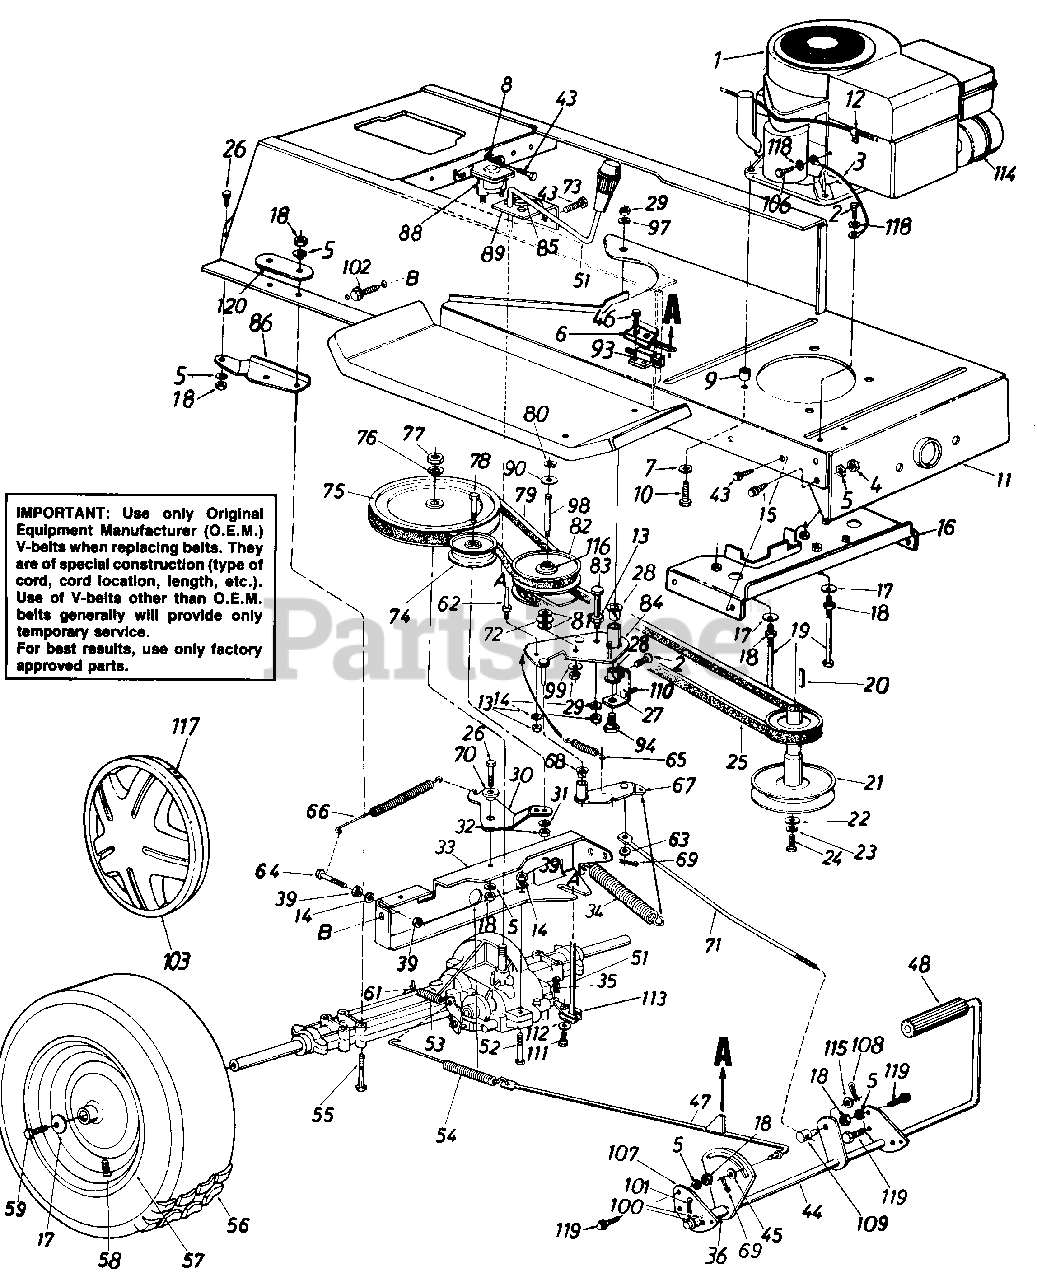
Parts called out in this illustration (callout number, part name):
1	Engine
2	Hex Wash. AB-Tap Scr. 5/16" x .75"
3	Electric Ground Wire
4	Hex Nut 5/16-24 Thd.
5	L-Wash. 5/16" I.D.
6	Switch Plate
7	Fl-Wash. .406" I.D. x 1.25"
8	Ext Wash 1/4 " I.D.
10	Hex L-Wash. Tap Scr. 3/8-16 x 15" Lg.
11	Lower Frame Ass'y.
13	Hex Nut 1/4-20 Thd.
14	L-Wash. 1/4" I.D.
15	Rib Neck Bolt 5/16-24 x .84" Lg.
16	Belt Guard Brkt. Ass'y.
17	Bell-Wash. .345" I.D. x .88"
18	Hex Nut 5/16-18 Thd.
19	Hex Bolt 5/16-18 x 4.0"
20	Sq. Key 1/4" x 1/4" x 2.00"
21	Engine Pulley
22	Fl-Wash. 7/16" I.D. x 1.25"
23	L-Wash. 7/16" I.D.
24	Hex Bolt 7/16-20 x 1.50" Lg.
25	Variable-Speed Belt
26	Hex Bolt 5/16-18 x .75" Lg.
27	Bearing Shaft Bracket Ass'y.
28	Flanged Nyliner Brg. 5/8" I.D. x .88" Lg.
29	Hex Nut 3/8-24 Thd.
31	L-Wash. 3/8" I.D.
32	Hex Nut 3/8-24 Thd.
33	Transaxle Support Brkt.
34	Ext. Spring .94" O.D. x 7.58"
35	Inter. Cott-Pin
36	Spacer.63" I.D.
39	Hex Nut 1/4-28 Thd.
43	Hex Wash. Hd. S-Tap Scr. 1/4-20 x .50" Lg.
44	Clutch/Brake Pedal Ass'y.
45	Fl-Wash.
46	Truss Mach. Scr. B-Tap Scr. #10 x .5" Lg.
47	Brake Rod Ass'y.
48	Foot Pad
51	Shift Lever Ass'y.
52	Hex Bolt 1/4-28 x 1.75" Lg.
53	Ext. Spring .38" O.D. x 2.5"
54	Ext. Spring 7.08"
55	Hex Bolt 5/16-18 x 2.75"
57	Wheel Rim Only
58	Air Valve
59	Hex Bolt 5/16-24 x .75" Lg.
61	Brake Return Spring Anchor
62	Belt Guard Pin 1/4-20 Thd.
63	Fl-Wash. .34" I.D. x .68" O.D.
64	Hex Bolt 1/4-28 x 1.25" Lg.
65	Ext. Spring
66	Ext. Spring .62" O.D. x 6.12"
68	Flanged Bearing
69	Cotter Pin 3/32" Dia.
70	Shoulder Spacer .27" Lg.
71	Speed Control Link
72	Truss Bearing .56 Dia. x 1 .25"
73	Shift Knob
74	Fl-ldler Pulley 3.25" x .75"
76	L-Wash. 1/2" I.D.
77	Hex Jam Nut 1/2-20 Thd.
78	Hex Bolt 3/8-24 x 1.75" Lg.
79	Variable Speed Belt
80	Snap Ring .56" Dia.
82	Variable Speed Pulley Ass'y. 5" O.D.
83	Hex Bolt 1/4-20 x 3.25" Lg.
90	Teflon Washer .565" I.D.
93	Safety Switch
94	Shld. Bolt 3/8-24 x 3.12n Lg.
97	Bell-Wash. .38" I.D. x .88n
98	Shaft .56" Dia. x 8 875n Lg.
99	Bell-Wash. .39" I.D. x 1.12n
100	Fl-Wash. .64" I.D. x .94"
101	Cotter Pin 1/8" Dia. x 1.25"
102	Hex Wash. Hd. Scr. 5/16-18 x.62" Lg.
103	Hub Cap
109	Ferrule
110	Hex Bolt 5/16-18 x 1 on Lg.- 0 (Gr. 5)
111	Hex Bolt 1/4-28 x .50" Lg.
112	Bell-Wash. .265" I.D. x .75"
113	Shift Lever Link Ass'y.
114	Muffler
115	Fl-Wash. .385" I.D. x .62"
116	Needle Brgs.
117	Spring Clip
118	External L-Wash. 5116" I.D.
119	Hex Wash. TT-Tap Scr. 5/16-1 8 x .75"
